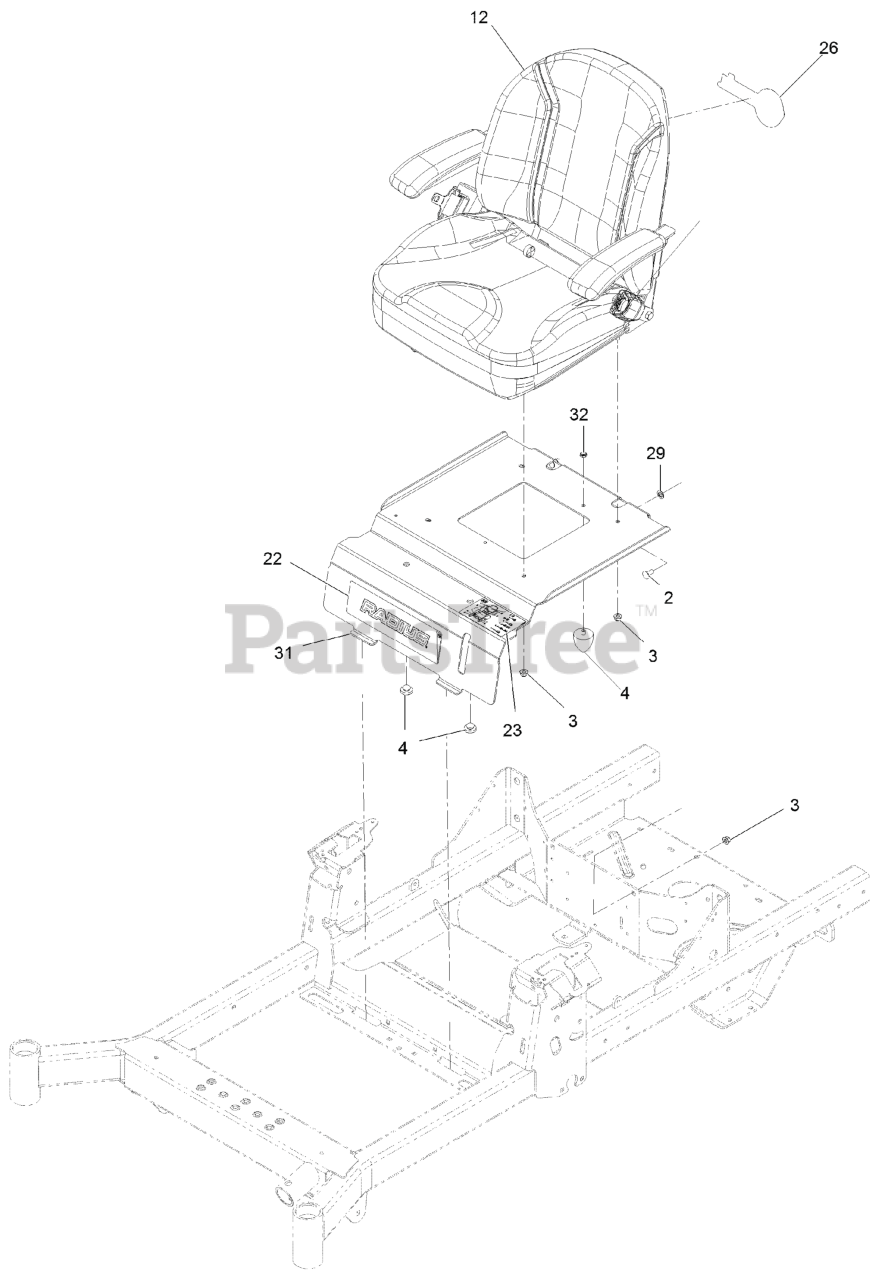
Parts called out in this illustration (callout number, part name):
2	SCREW-CARR
3	NUT-HF, NI
4	BUMPER-SEAT
4	BUMPER-RUBBER
12	ASM-SEAT EXMARK
22	DECAL-RADIUS LOGO
23	DECAL-AID, SERVICE
26	DECAL, EXMARK LOGO
29	Washer-Retaining
31	PLATE-FIXED SEAT
32	NUT-LOCK, NI
